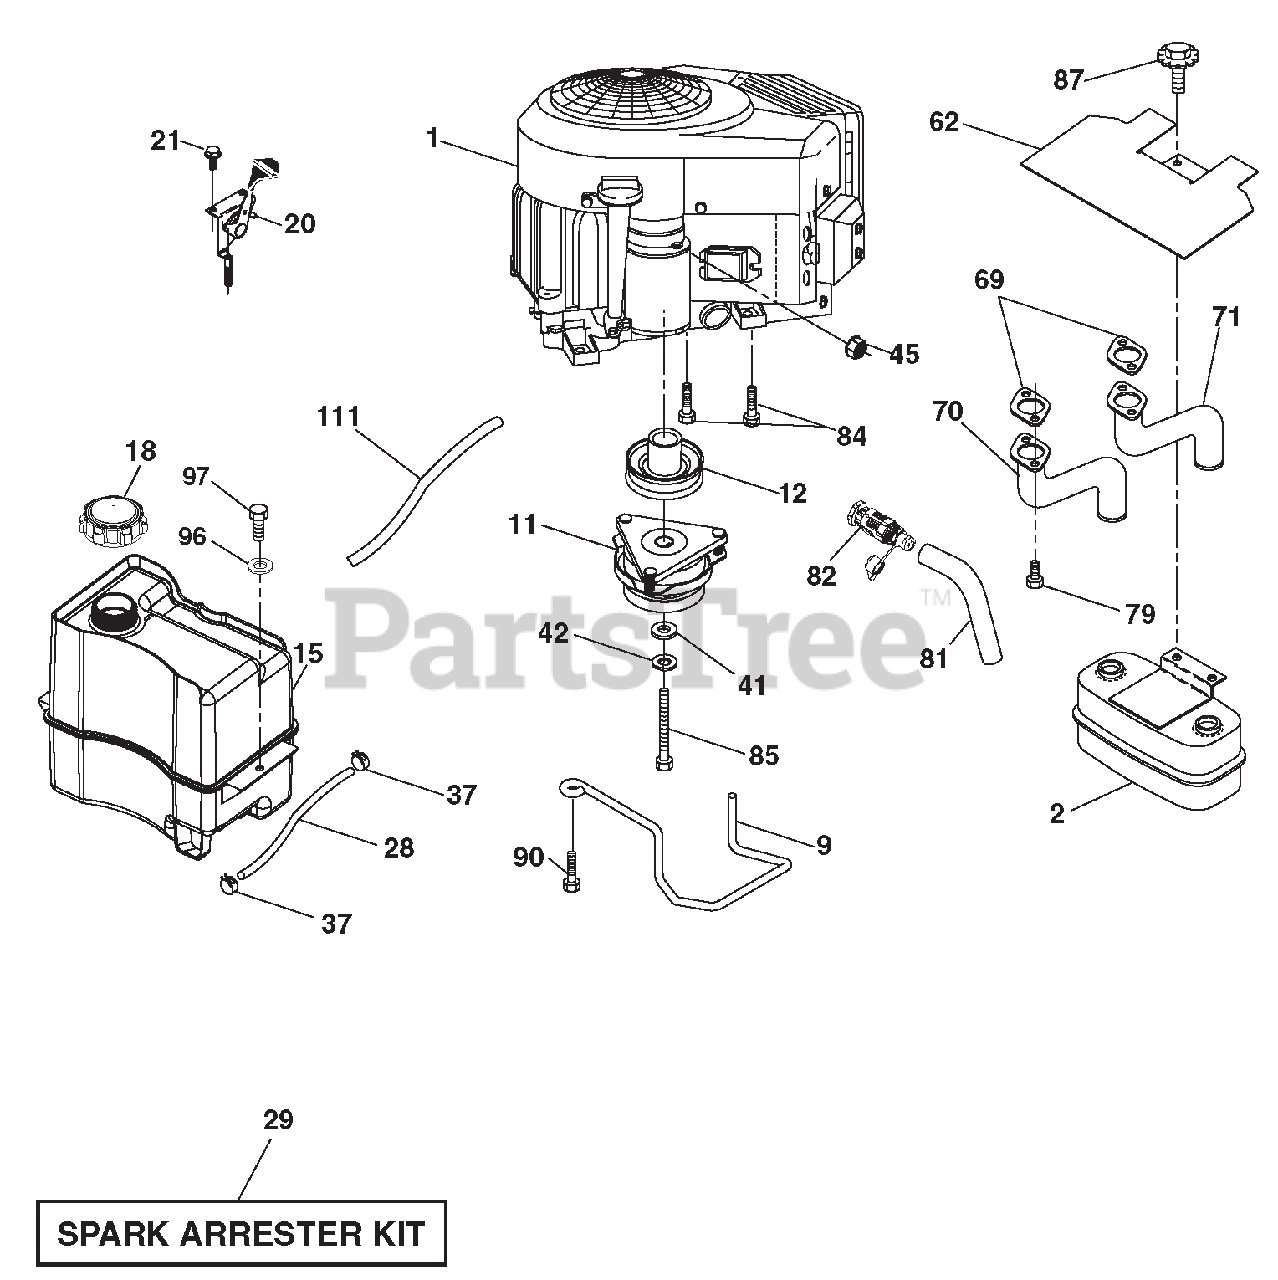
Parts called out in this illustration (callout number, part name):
1	ENGINE BRIGGS 407777-2217-G1
2	MUFFLER ASM.TWIN.LO-TONE
9	KEEPER.BELT.ENGINE.4.25"NSTG
11	CLUTCH.ELECTRIC.LT.1"CRANK
12	PULLEY.ENGINE.TUFFTORQE.1"CRK.
15	TANK FUEL SIDE FILL 3.OO GA.
18	CAP FUEL
20	CONTROL THROTTLE/CHOKE
28	LINE.FUEL.22"FRONT.EMIS.CA.LP
29	KIT.SPARK ARRESTOR(392390 B&S)
37	CLAMP.HOSE.BLK.
41	WASHER.1-1/2 ODX15/32 IDX.250
42	WASHER.LOCK.HVY HLCL.SPR.7/16
45	Nut, Keps Hex 1/4-20 unc
62	SHIELD.HEAT.MUFFLER.
69	GASKET MUFFLER
70	EXHAUST TUBE LH
71	EXHAUST TUBE RH
79	SCREW SOCKET HEAD 5/16-18 X 1
81	TUBE.DRAIN.OIL.EASY
82	VALVE OIL DRAIN
84	Screw 3/8-16 x <
85	BOLT.HEX.7/16-20X4XGR5-1.5THR.
87	BOLT.5/16-18 UNC X 1 W/SEMS.BL
90	SCREW.3/8-16X1.SMGML.TAP/R.BLK
96	WASHER.9/32 X 7/8 X 16GA.
97	SCREW.HEXWSH.THDROL.1/4-20X3/4
111	PURGE.LINE.CARB 3/16
